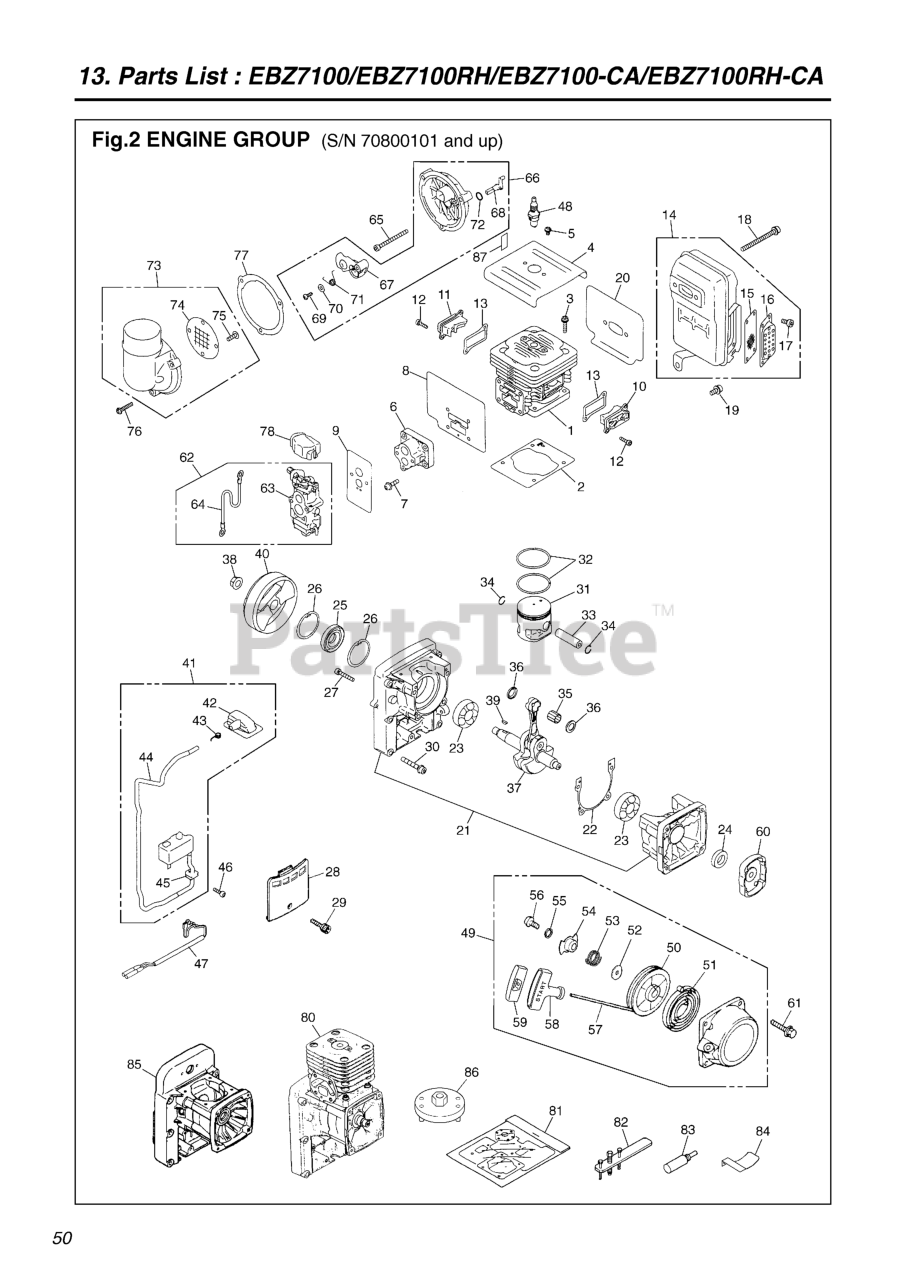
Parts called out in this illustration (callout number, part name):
1	CYLINDER
2	GASKET, BASE
3	BOLT
4	PLATE, CYL
5	SCREW TORX
6	INSULATOR
7	BOLT
8	GASKET, INSULATOR
9	GASKET, CARB.
10	COVER, TR (S)
11	COVER, TR (F)
12	BOLT TORX
13	GASKET, TR
14	MUFFLER ASSY
15	Arrester
17	Bolt
18	BOLT TORX
19	BOLT
20	GASKET
21	CRANKCASE-CASE
22	GASKET, CASE
23	BEARING
24	SEAL
25	SEAL
26	SNAP RING
27	BOLT
28	COVER
29	BOLT TORX
30	BOLT TORX
31	PISTON
32	RING, PISTON
33	PIN
34	SNAP RING
35	BEARING
36	WASHER
37	CRANKSHAFT-C
38	NUT, M10
39	KEY
40	ROTOR
41	COIL ASSY
42	CAP
43	SPRING
44	TUBE
45	GROMMET
46	BOLT TORX
47	CORD-C
48	USE T110873110
49	RECOIL ASSY (RPLS -7511)
50	REEL (REPLACES -75C1)
51	SPRING
52	WASHER (REPLACES -75M0)
53	SPRING, FRICTION (RPLS. -75L1)
54	PLATE, FRICTION (RPLS. -75K1)
55	WASHER (REPLACES -75W0)
56	SCREW
57	ROPE
58	KNOB
59	COVER KNOB
60	PULLEY (RPLS 848-H00-7520)
61	BOLT, TORX
62	CARBURETOR SET
63	CARBURETOR ASSY
64	Cord
65	BOLT
66	CUP ASSY
67	PLATE, CHOKE
68	LEVER
69	SCREW
70	WASHER
71	SPRING
72	O-RING
73	COVER ASSY. (REPLACES -8340)
74	SCREEN
75	SCREW
76	SCREW
77	GASKET,CUP
78	COVER
80	SHORT BLOCK
81	GASKET KIT
82	PULLER ASSY
83	STOPPER (TOOL)
84	GAUGE
85	CRANKCASE-A
86	PULLER
87	LABEL, CHOKE
